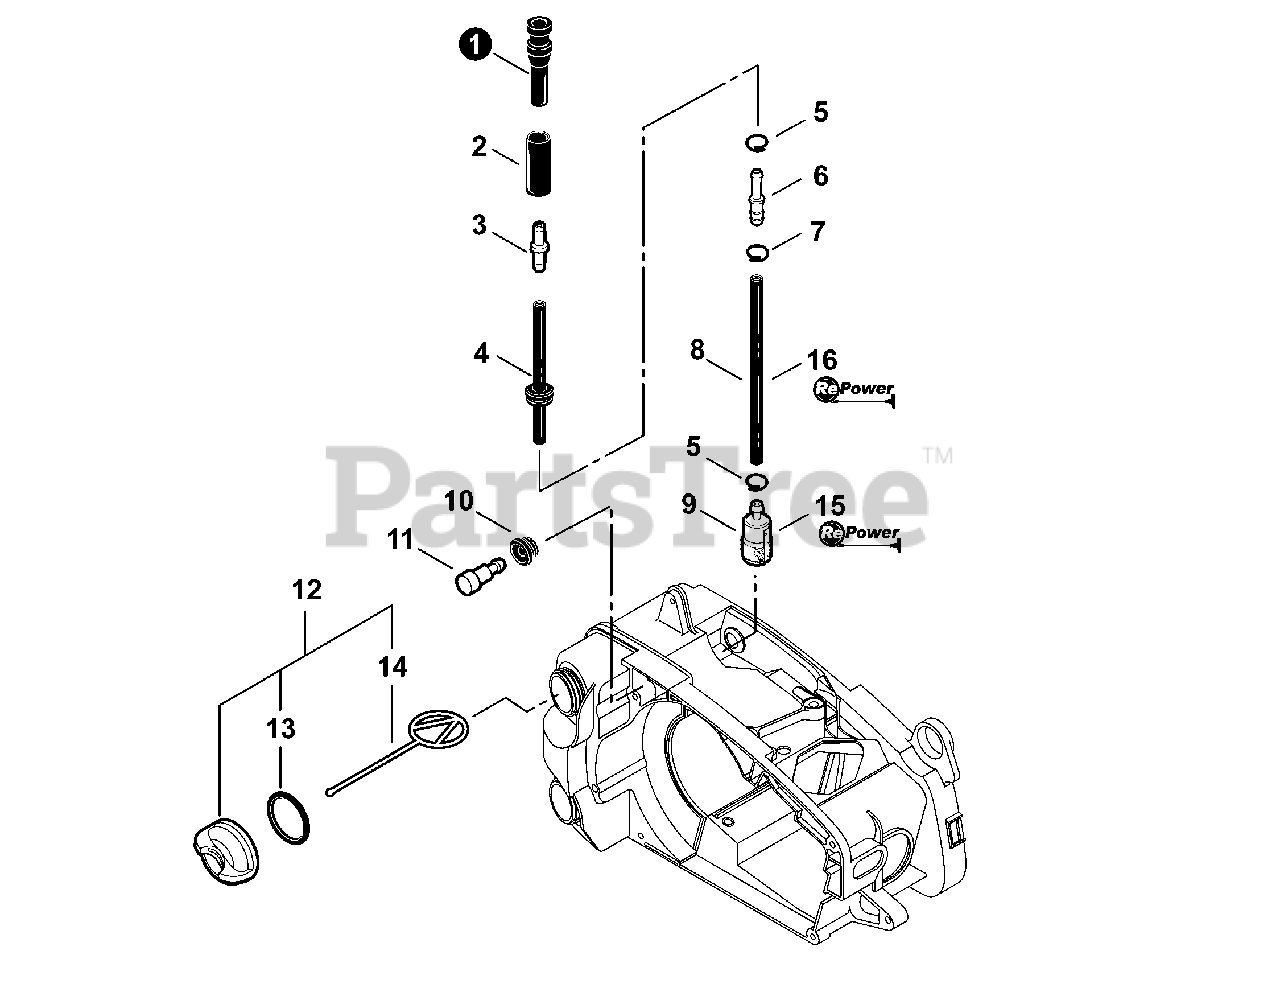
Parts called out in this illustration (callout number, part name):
1	PIPE, FUEL
2	TUBE 6.5×30
3	CONNECTOR, PIPE
4	PIPE ASSY, FUEL
6	CONNECTOR, PIPE 5×3.5
8	PIPE, FUEL 3×5×95
9	FILTER, FUEL
10	GROMMET, FUEL
11	VENT ASSY
12	CAP ASSY, FUEL - ORANGE
14	CONNECTOR, CAP L= 60mm
15	TUNE-UP KIT - REPOWER
16	PIPE, BULK - REPOWER 3×5mm BLACK
